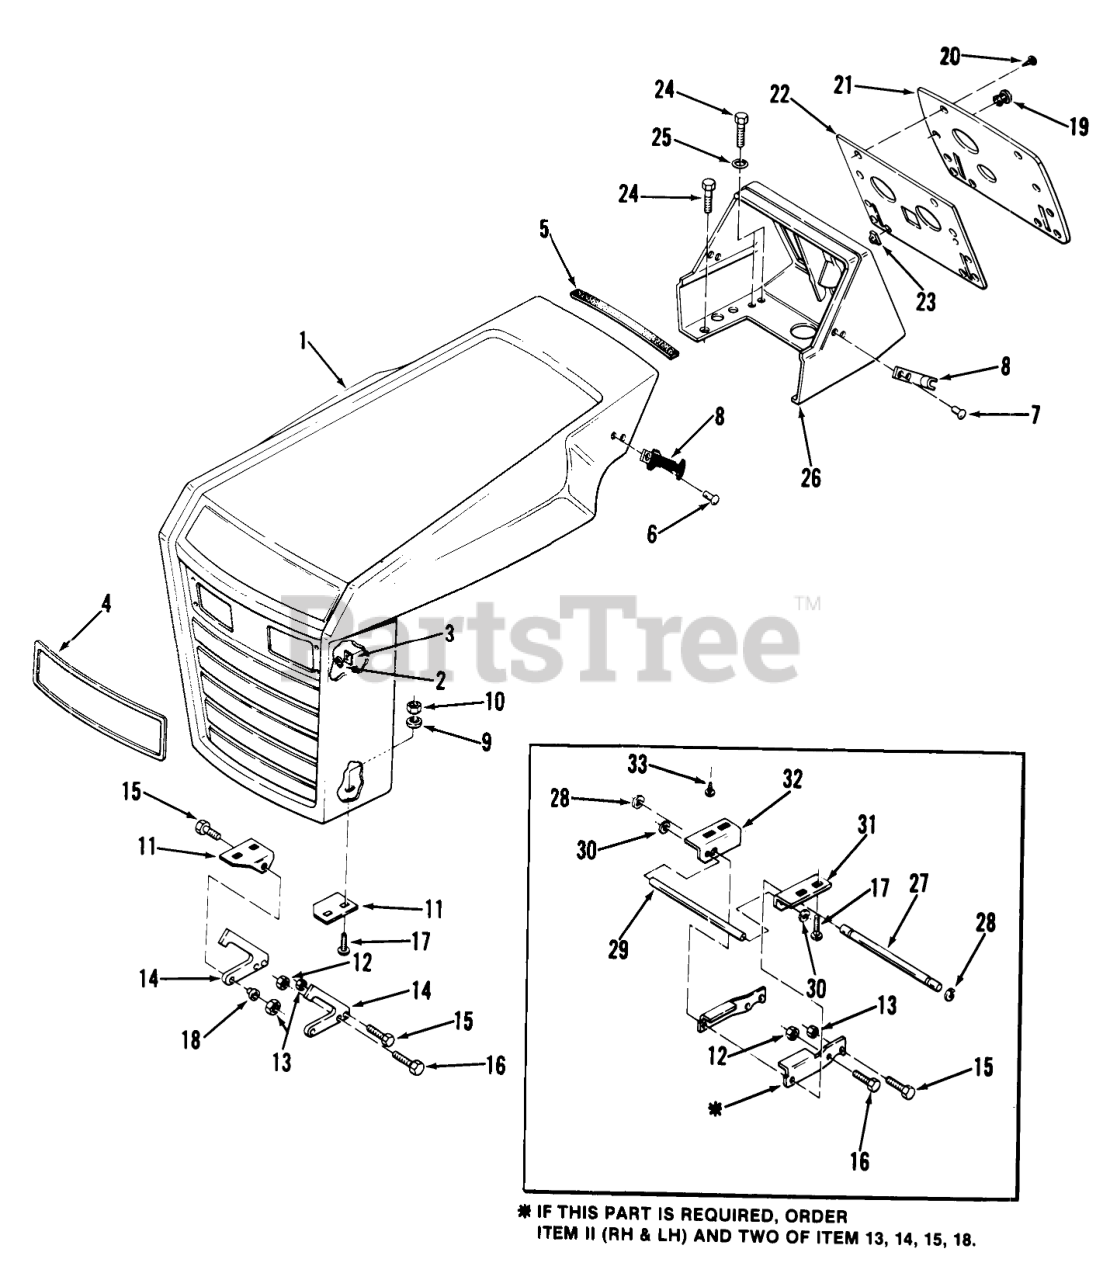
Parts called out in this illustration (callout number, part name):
2	WASHER
3	SPEED NUT
4	GRILL PLATE
5	TRIM-CONSOLE
6	RIVET -4
7	RIVET
8	ASSY-FLEX DRAW LATCH
10	Nut
11	BRKT-HOOD PIVOT LH
11	BRKT-HOOD PIVOT RH
12	Nut
13	Nut
14	BRACKET-HOOD SUPT
15	Bolt
16	Bolt
17	Bolt-Carriage
18	BUSHING-PIVOT
19	PLUG BUTTON
20	SCREW BLACK
21	PLATE-INSTRUMENT
22	Back-Up Plate
23	SPEED NUT
24	SCREW
25	WASHER 5/16 SAE
26	Console
27	ROD-GRILL PIVOT
28	RING-RETAINING
29	ROD-HOOD STOP
30	SPEED NUT
31	BRKT-HOOD PIVOT LH
32	Pivot Bracket Hood RH
33	GROMMET
